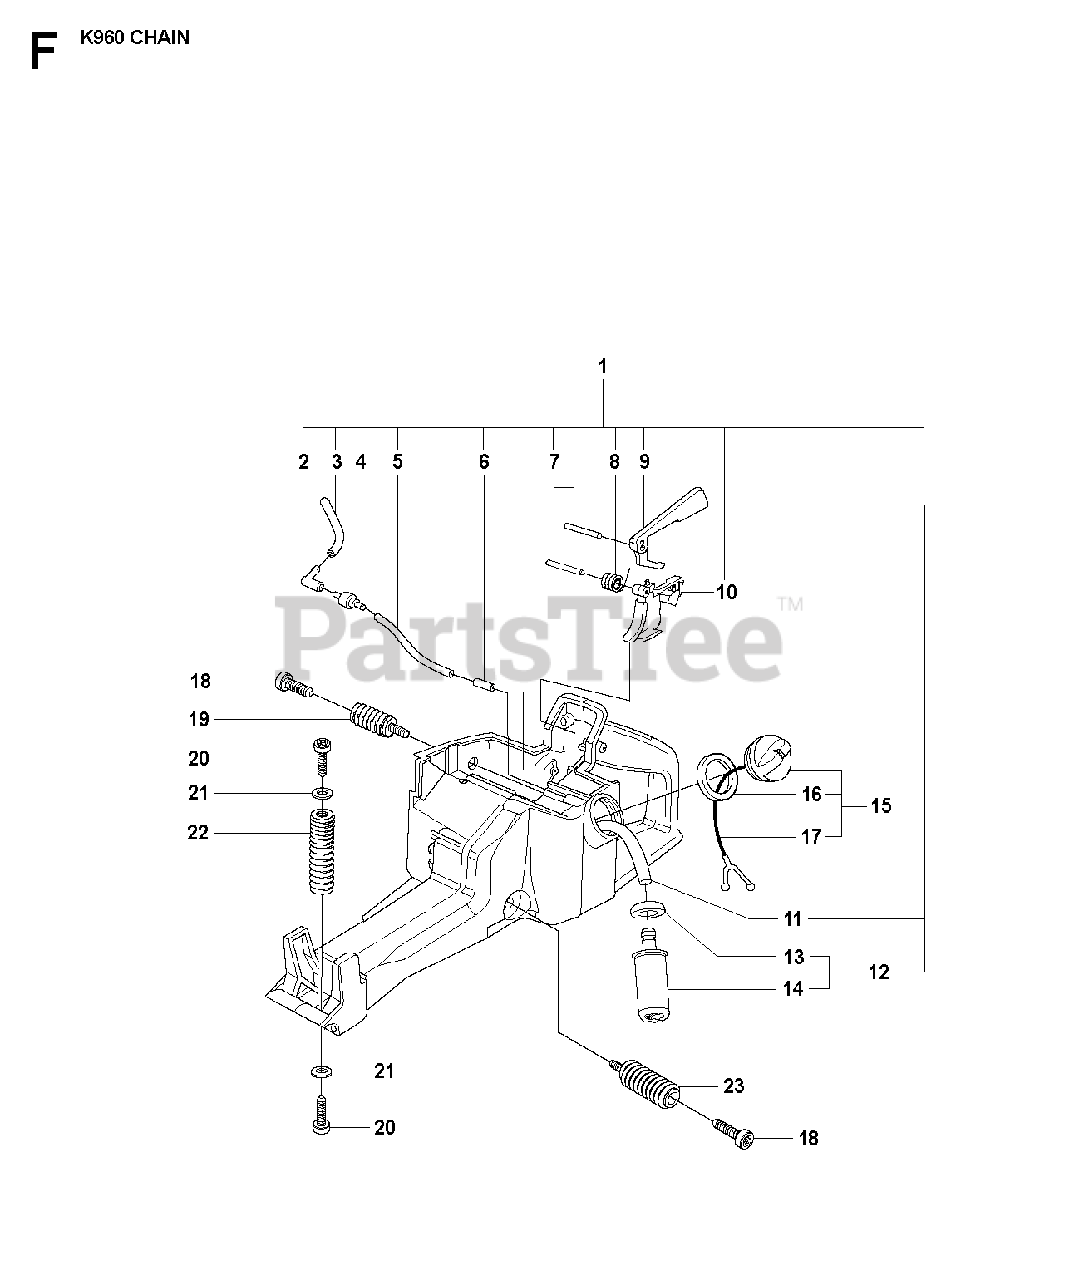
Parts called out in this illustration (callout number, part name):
1	FUEL TANKIncl. 2 - 12
2	CONNECTION BEND
3	FUEL HOSE
7	PARALLEL PIN
8	SPRING THROTTLE TRIG
9	THROTTLE LOCKOUT
11	FUEL HOSE
12	FUEL FILTERIncl. 13, 14
15	TANK CAP ASSYIncl. 16, 17
18	SCREW ITXSCM
19	ANTIVIBRATION ELEMENT
20	SCREW ITXSCM
22	ANTIVIBRATION ELEMENT
